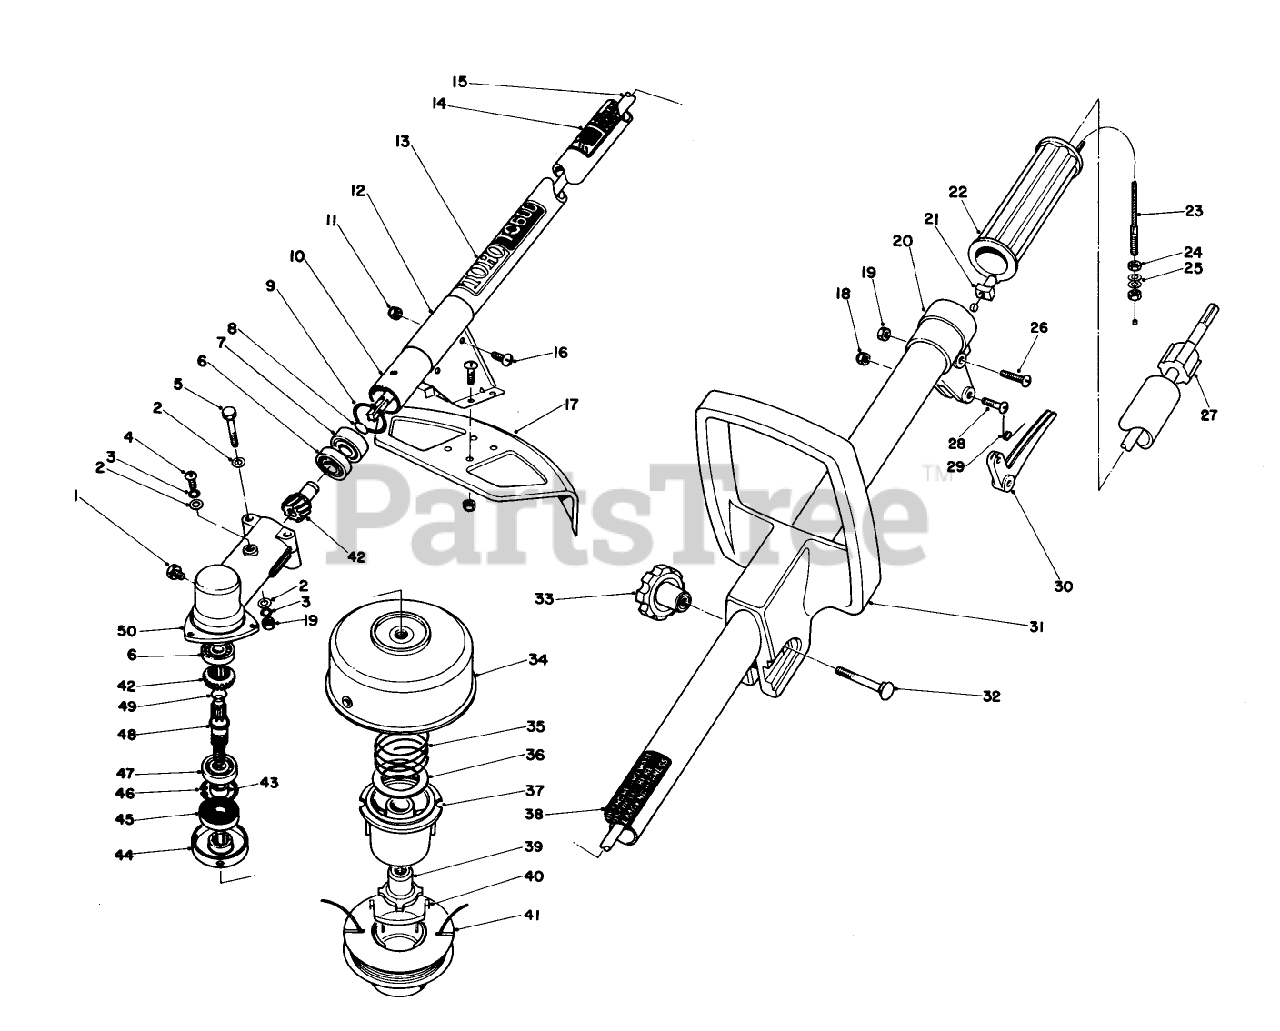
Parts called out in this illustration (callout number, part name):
11	NUT-LOCK, NI
16	SCREW-PPH
32	BOLT-CARR
35	SPRING
36	WASHER-FLAT
37	SPOOL CORE
39	LH DRIVER
